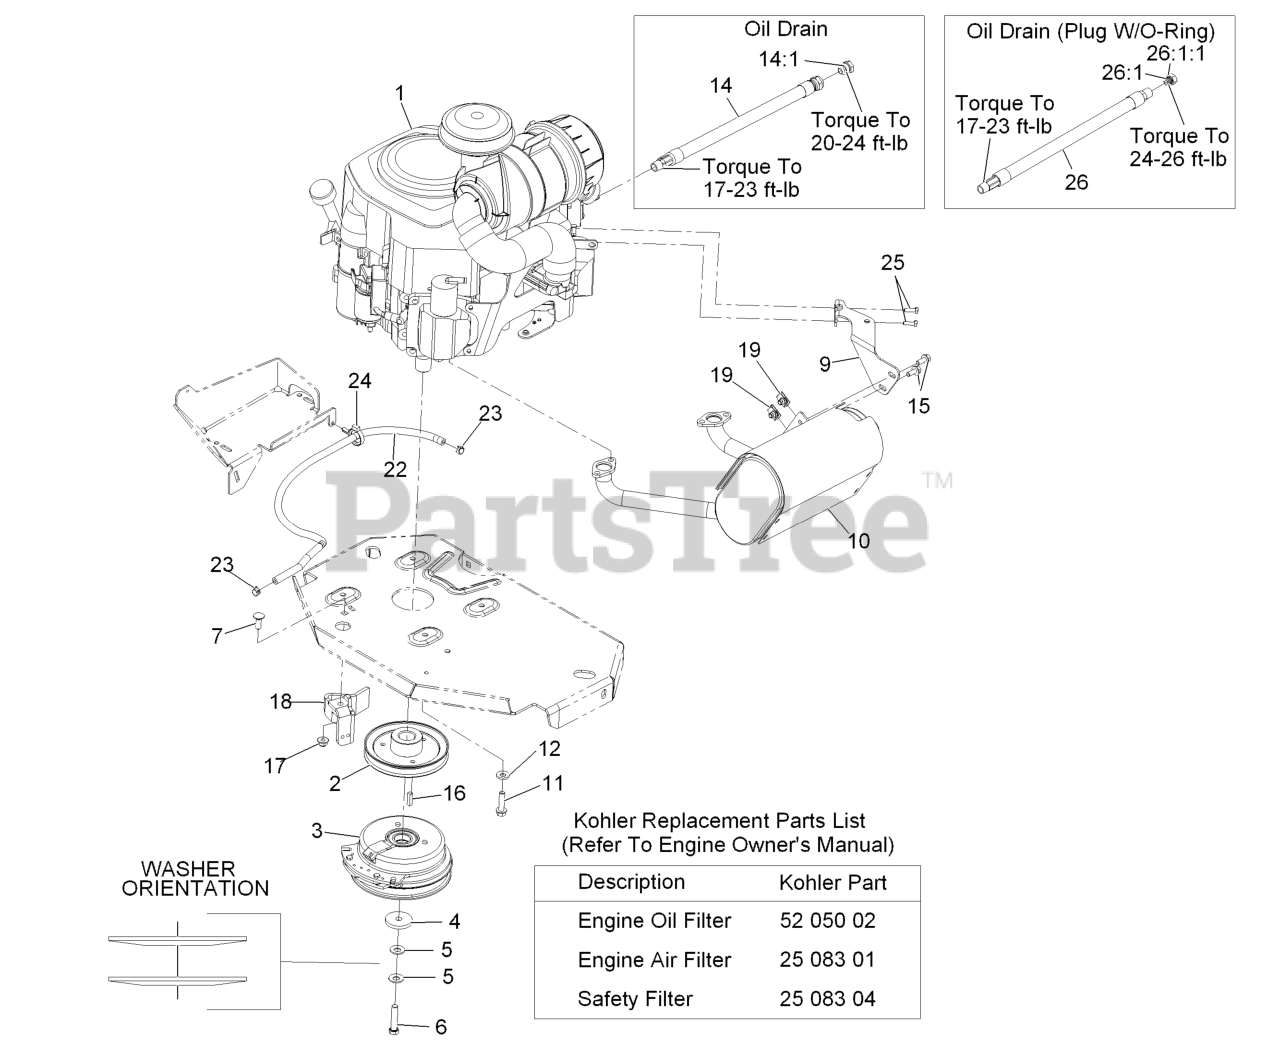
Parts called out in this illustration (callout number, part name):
1	Engine,Koh 27hp Hd
2	SHEAVE
3	CLUTCH KIT
4	WASHER-CLUTCH
5	WASHER-SPRING
6	SCREW-HH W/LOCTITE
7	SCREW-CARR
9	MUFFLER BRACKET KIT
11	SCREW-HWH
12	WASHER-BELLEVILLE
15	SCREW-HHF
17	NUT-HF, NI
18	CLUTCH-ANCHOR
22	HOSE-FUEL
23	CLAMP-HOSE
24	CLAMP-HOSE
25	SCREW-HH M6-1 X 20Mm W/Patch
26	OIL DRAIN HOSE ASM
26:1	PLUG-HH
26:1:1	O-RING
